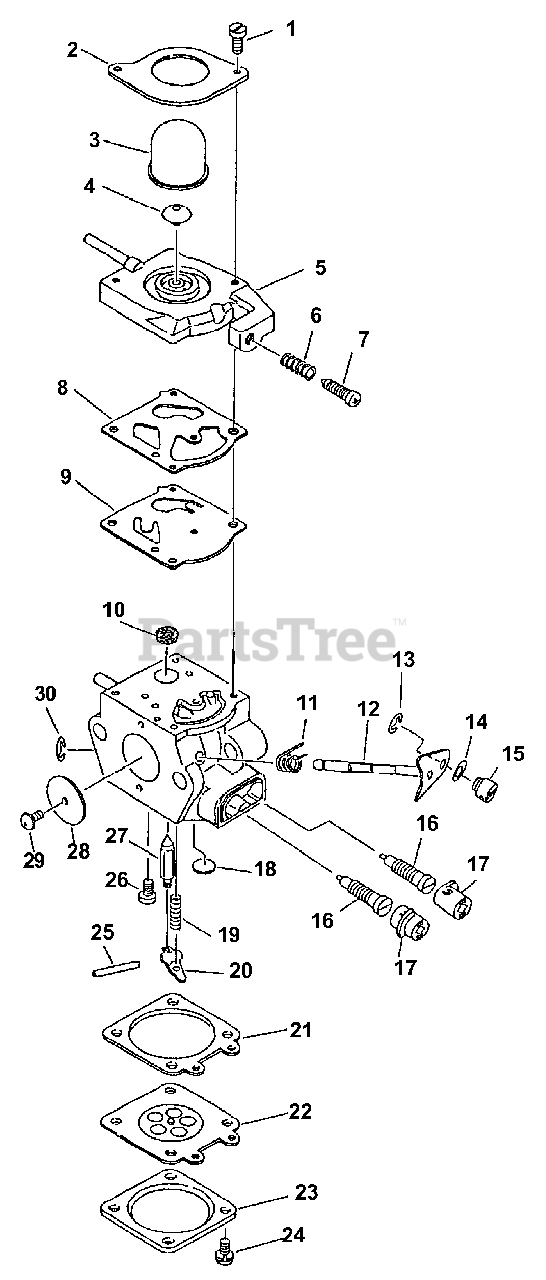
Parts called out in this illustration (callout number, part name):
1	SCREW, PUMP COVER
2	RETAINER, PURGE BULB
3	BULB, PURGE
4	VALVE, CHECK
5	BASE, PURGE
6	SPRING, IDLE ADJUST
7	SCREW, IDLE ADJUST
8	GASKET, PUMP
9	DIAPHRAGM, PUMP
10	STRAINER
11	SPRING, THROTTLE RETURN
12	SHAFT, THROTTLE
13	RING, RETAINING
16	NEEDLE - MIXTURE
17	CAP, LIMITER
18	PLUG, WELCH
19	SPRING, METERING LEVER
20	LEVER, METERING
21	GASKET, METERING
22	DIAPHRAGM, METERING
23	COVER, METERING
24	SCREW
25	PIN, METERING LEVER
26	SCREW
27	VALVE, INLET NEEDLE
28	VALVE, THROTTLE
30	RING, RETAINING
30	REPAIR KIT
30	DIAPHRAGM/GASKET KIT
